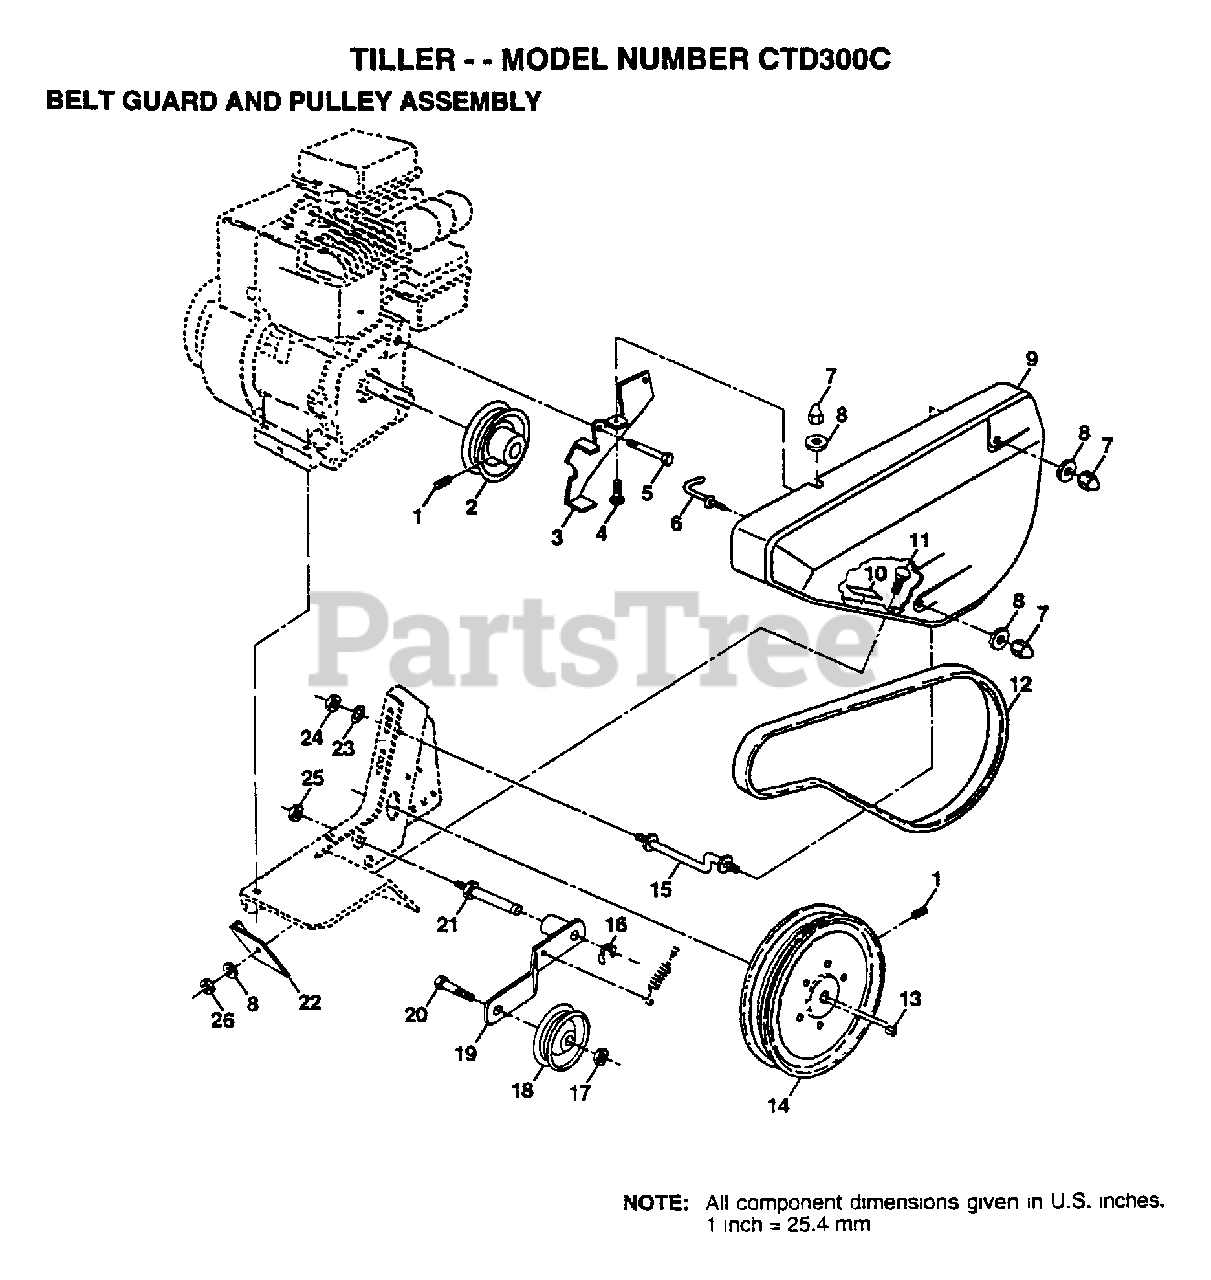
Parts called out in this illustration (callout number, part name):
1	SET SCREW
4	BOLT
7	NUT-CAP TI
8	WASHER
9	GUARD.BELT.TILLER
10	PAD IDLER TI
11	BOLT T
13	KEY T
14	TRANS SHEAVE RT
16	KLIP RING TI
17	NUT
19	IDLER ARM TI
21	SHAFT IDLER TI
22	SHIELD-DIRT TI
23	LOCKWASHER
25	JAM NUT TI
